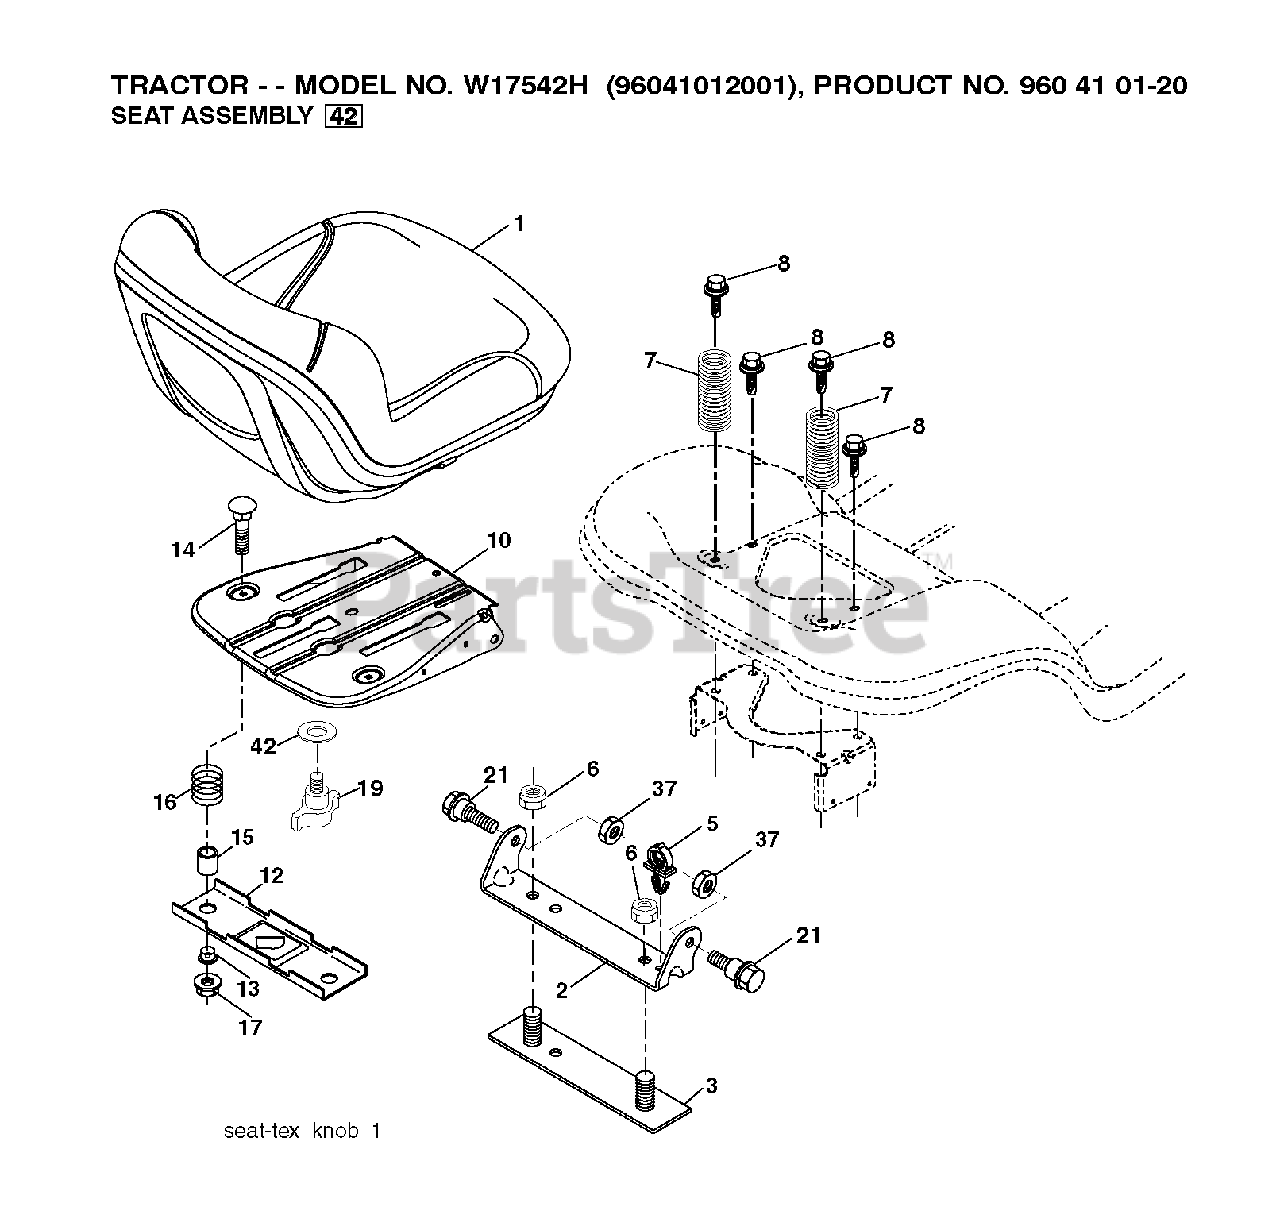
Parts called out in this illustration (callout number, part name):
1	SEAT.TG130.BLACK.NO/LOGO.
2	BRKT.PIVOT.FENDER
5	PUSH CLIP
6	NUT
7	SPRING COMPRESSION
8	BOLT, 5/16-18 X 1 3/4
10	PAN.ASM.SEAT.SHORT
12	BRKT.MNT.OPC.SW.SEAT.
14	BOLT.ROUND.HEAD.SQUARE.NECK
15	SPACER SPLIT 28X.96
16	SPRING COMPRESSED
17	NUT T
19	KNOB.SEAT.ADJ.
21	BOLT.SHOULDER.5/16-18
37	NUT.71038.31-18.HEX.NYLOCK
42	WASHER.CUP.SEAT.
